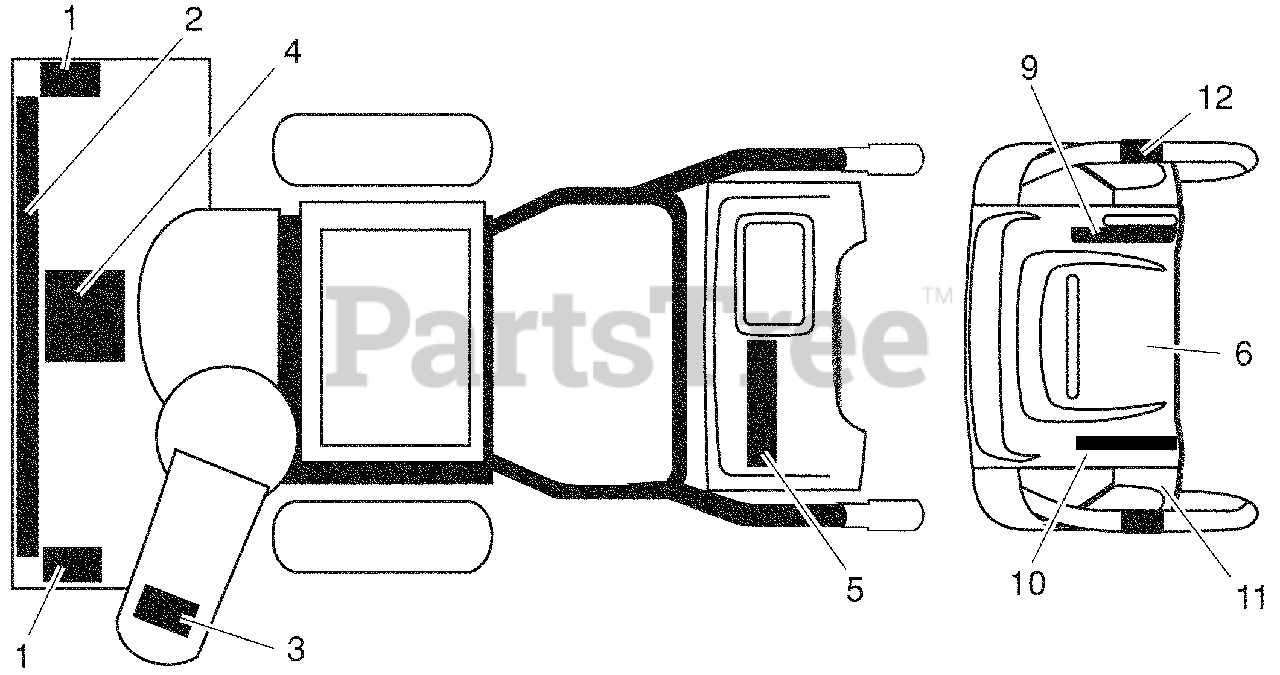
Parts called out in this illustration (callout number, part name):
1	DECAL, DANGER
2	DECAL, HUSQ
3	DECAL, DANGER, DEFLECTOR
4	DECAL, DANGER
5	DECAL, HUSQ (10527SB-LS)
6	DECAL, INSTRUCTION
7	DECAL, TRACTION LEVER
8	DECAL, AUGER LEVER
9	DECAL, SPEED CONTROL
10	DECAL, REM DEFLECTOR LT. E/F
